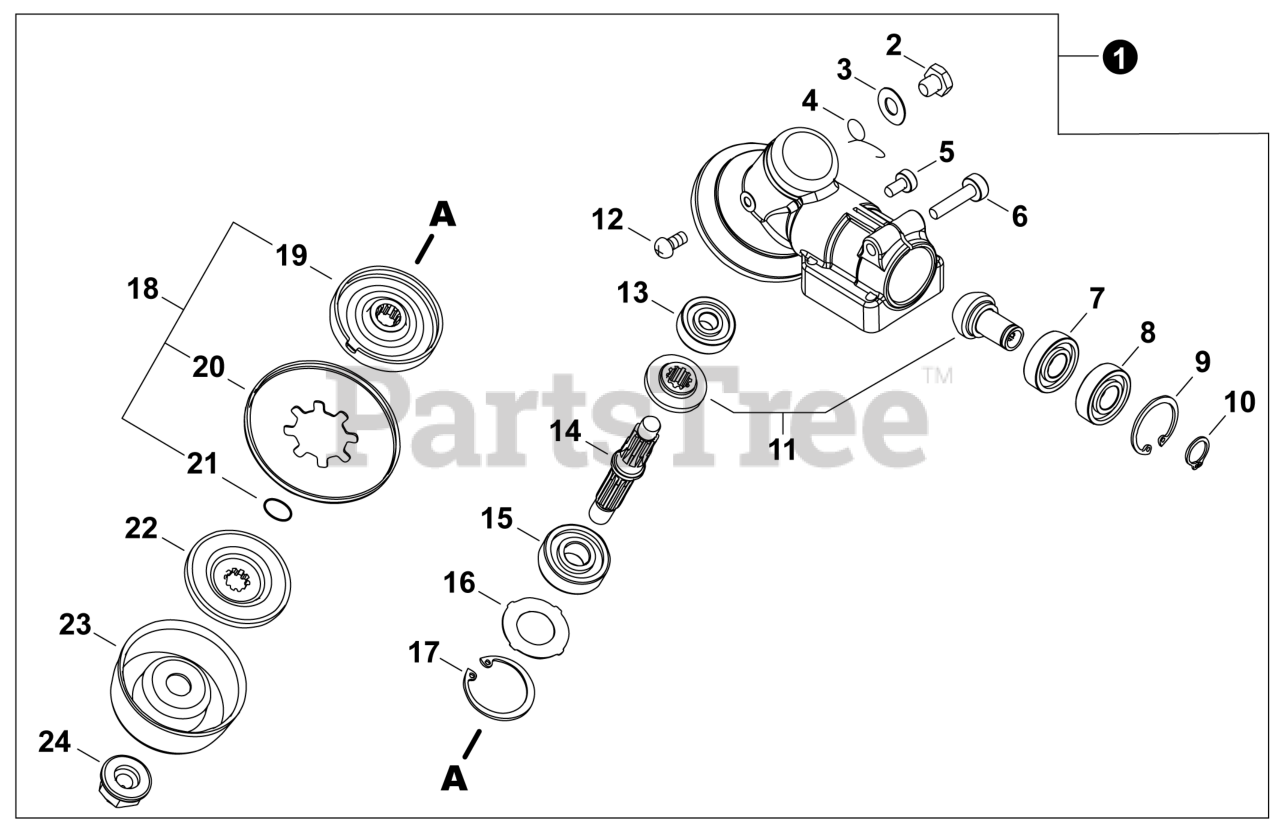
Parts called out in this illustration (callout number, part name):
1	CASE, GEAR
2	BOLT M8x8
3	WASHER 8.5x18x0.8T
4	SPRING, TORSION
5	BOLT, TORX 5x10
6	BOLT, TORX 6x30
7	BEARING, BALL 6001
8	BEARING, BALL 6001Z
9	RING, SNAP 28
10	RING, SNAP 12
11	GEAR SET
12	SCREW 4x6
13	BEARING, BALL 629
14	SHAFT, GEAR
15	BEARING, BALL 6201
17	RING, SNAP 32
18	RETAINER SET, BLADE
19	RETAINER, BLADE
20	PLATE, ADAPTOR - UPPER
21	O-RING 12 MM
22	PLATE, ADAPTOR - LOWER
24	NUT, LOCK 10 - NYLON INSERT
